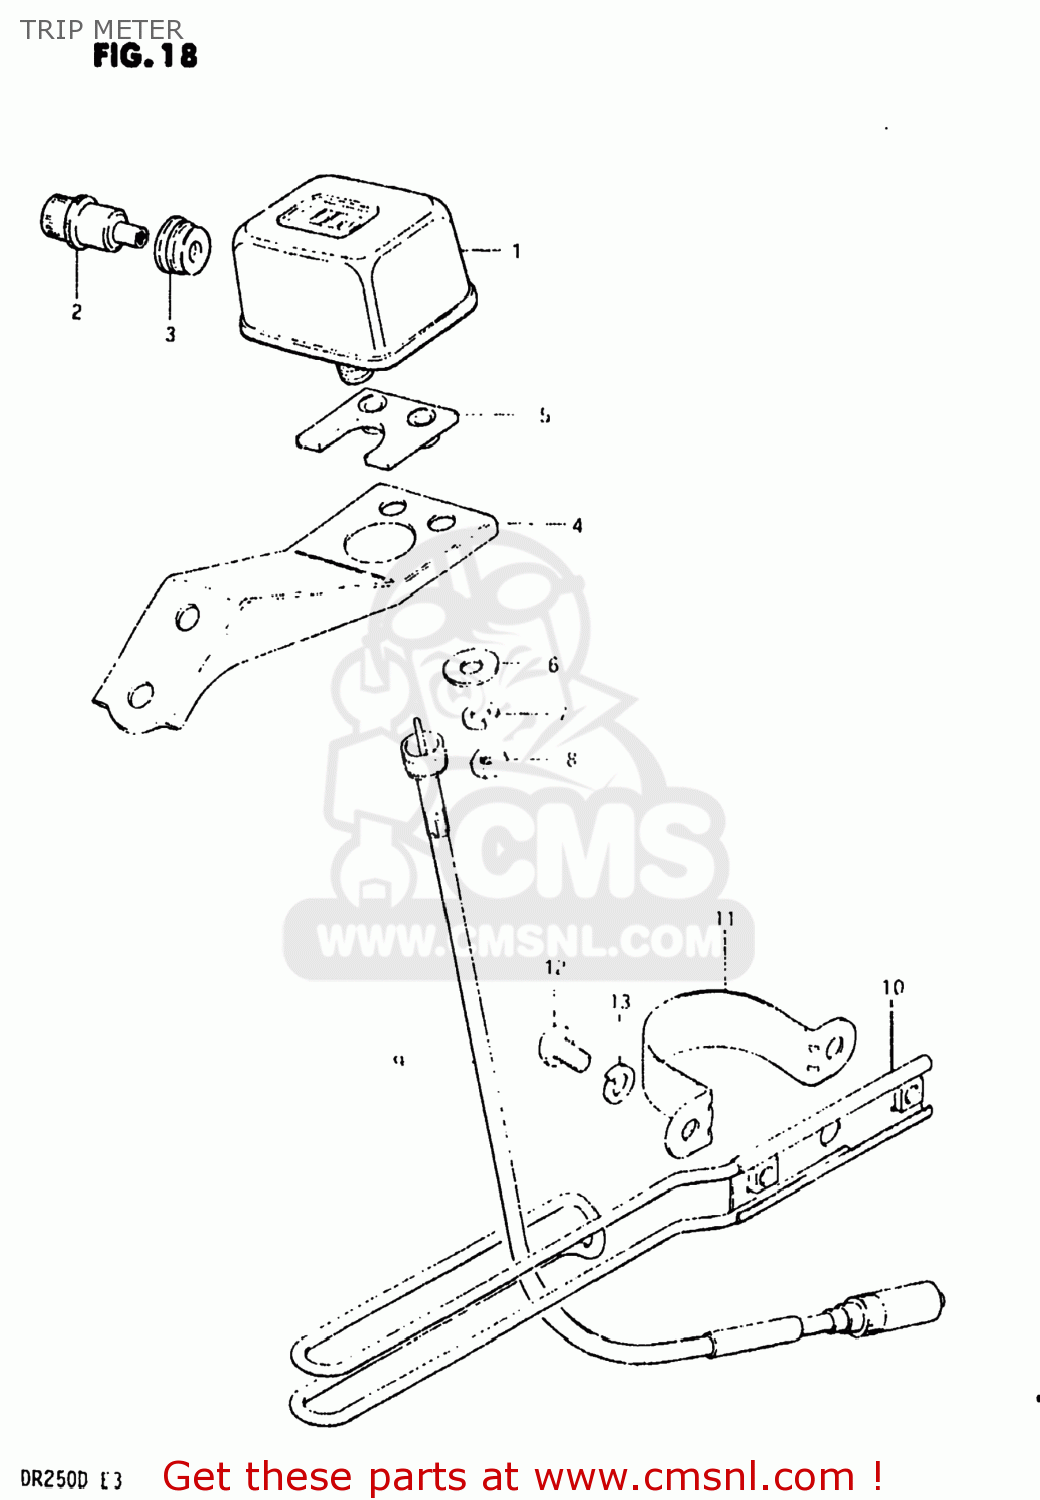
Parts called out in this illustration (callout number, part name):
1	TRIP METER
2	KNOB,TRIP METER
3	COVER,TRIPMETER KNOB
4	BRACKET,TRIPMETER
5	CUSHION,TRIPMETER
6	WASHER,METER
7	LOCK WASHER
8	NUT
9	CABLE ASSEMBLY,SPEEDOMETER
10	CLAMP,SPEEDOMETER CABLE
11	CLAMP
12	SCREW 6X12
13	LOCK WASHER
